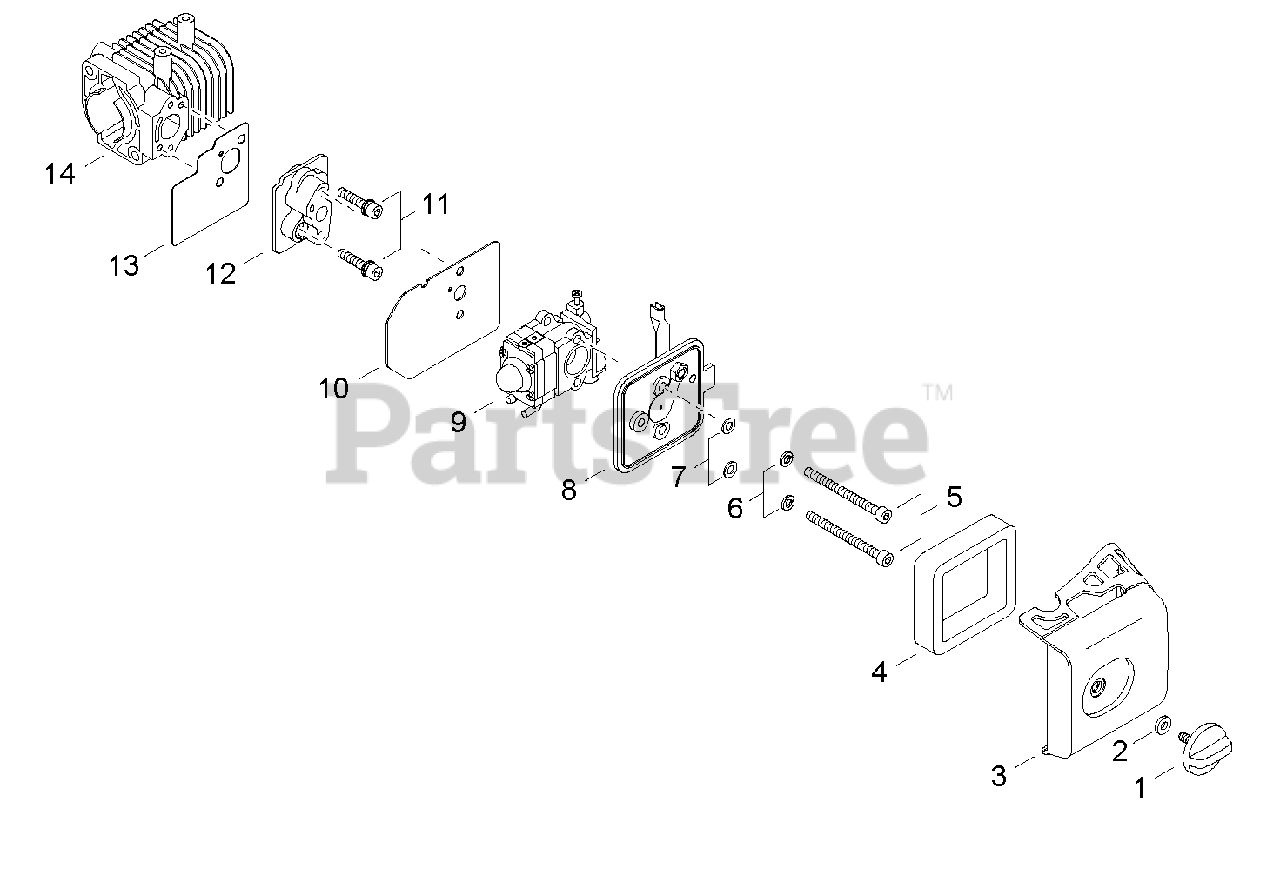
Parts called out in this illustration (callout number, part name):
1	THUMBSCREW
2	WASHER 5
3	COVER, AIR FILTER
4	FILTER, AIR
5	BOLT 5×55
6	WASHER, SPRING 5
7	WASHER, FLAT 5.5×10×0.8
8	CASE ASSY, AIR FILTER
9	CARBURETOR - WYJ-488A
10	GASKET, CARBURETOR
11	BOLT M5×30
12	INSULATOR, INTAKE
13	GASKET, INTAKE
14	CYLINDER
